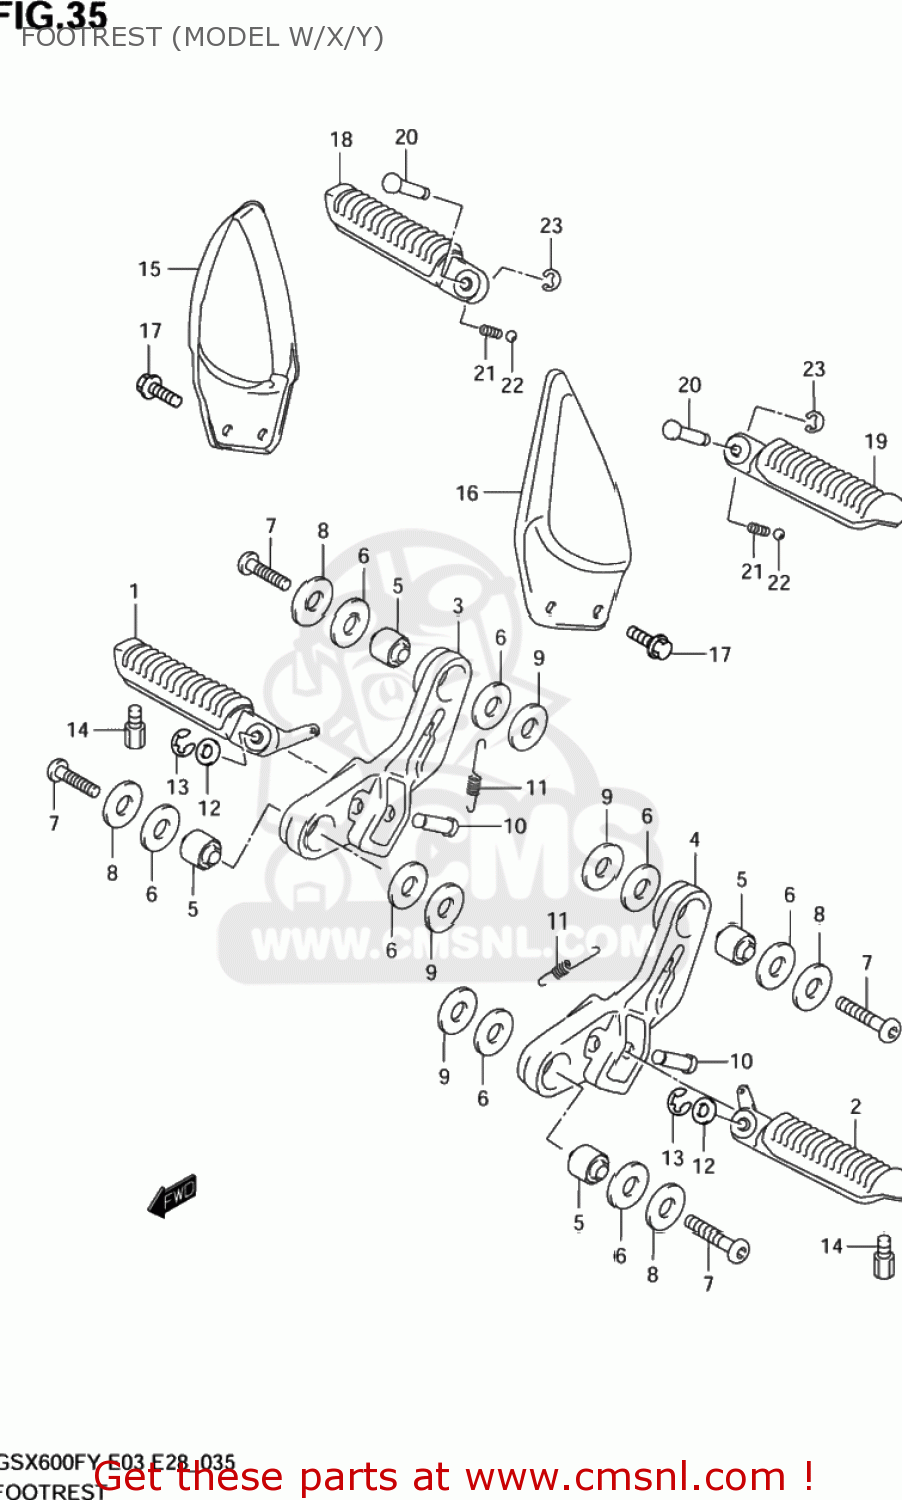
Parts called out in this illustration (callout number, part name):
1	BAR,FRONT FOOTREST,RIGHT
2	BAR,FRONT FOOTREST,LEFT
3	HOLDER,FR FOOTREST,R
4	HOLDER,FR FOOTREST,L
5	BUSH(8.4X20X18)
6	WASHER(12.5X30X2)
7	BOLT(8X33)
8	WASHER (8.5X30X2.3)
9	WASHER(8.5X30X2.3)
10	PIN(8X33.2)
11	SPRING
12	WASHER
13	E.RING
14	BOLT,BANK SENSOR
15	GUARD,FR FOOTREST,R
16	GUARD,FR FOOTREST,L
17	BOLT(8X16)
18	BAR,PILLION FOOTREST,R
19	BAR,PILLION FOOTREST,L
20	PIN
21	SPRING
22	BALL
23	E.RING
